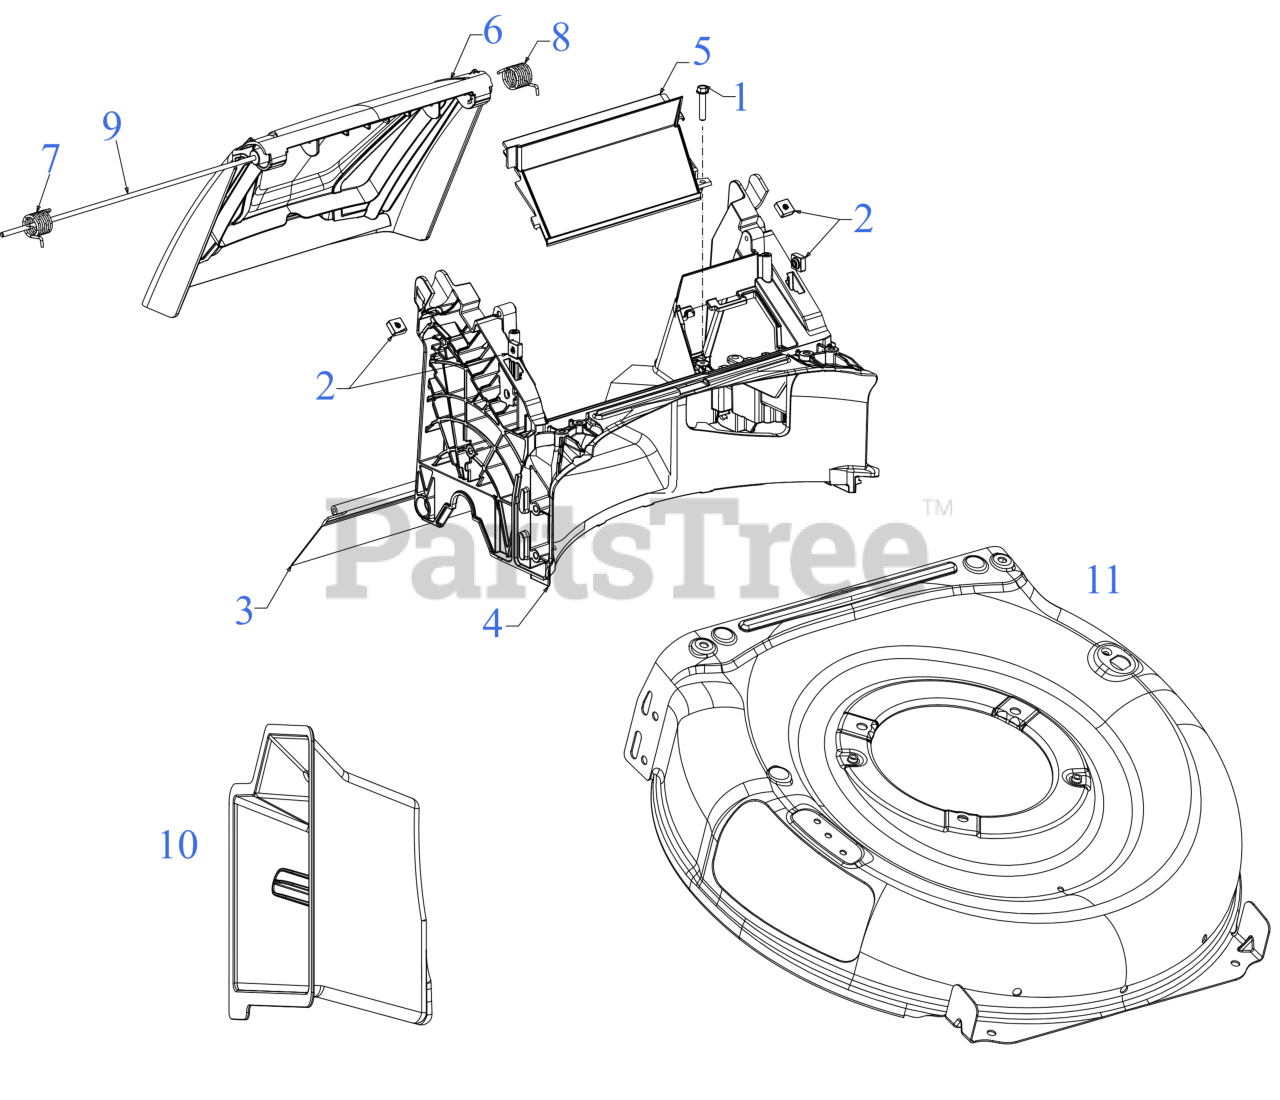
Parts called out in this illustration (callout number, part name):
1	SCREW 1/4-15 x 1.250
2	SQUARE LOCK NUT 1/4X20
3	TRAILSHIELD
4	21" BAFFLE ASSEMBLY (REAR)
5	21" BAFFLE ASSEMBLY (REAR)
6	21" BAFFLE ASSEMBLY (REAR)
7	TORSION SPRING (RH)
8	TORSION SPRING (LH)
9	21" BAFFLE ASSEMBLY (REAR)
